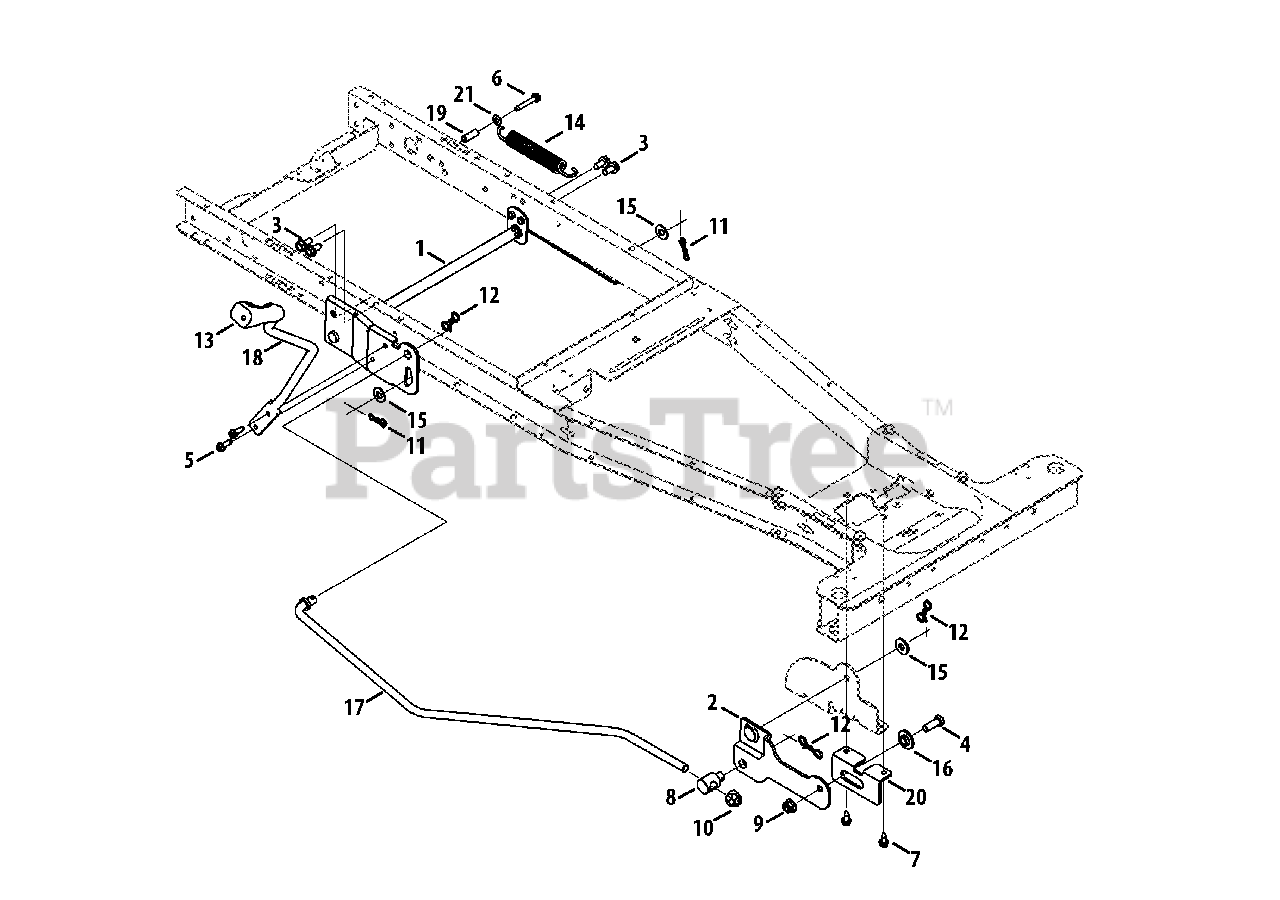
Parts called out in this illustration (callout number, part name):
1	Lift Assembly Shaft
2	Front Hanger Bracket Assembly
3	Tap Screw, 5/16-18, .750
4	Hex Head Screw, 3/8-16, 1.00
5	Tap Screw, 1/4-20, 0.750
6	Screw, 1/4-20, 1.50
7	Tap Screw, 1/4-20 X .625
8	Ferrule, .50 X .50
9	Flange Lock Nut, 3/8-16
10	Flex Lock Nut, 1/2-13
11	Bow-Tie Cotter Pin, 72
12	Bow-Tie Cotter Pin, 91
13	Grip Handle, 1/2
14	Extension Spring, .85 OD X 5.915 LG
15	Flat Washer, .406 X .875 X .059
16	Shoulder Spacer, .625 ID X .169
17	Lift Link Rod
18	Deck Lift Rod
19	Spacer, .260 x .375 x 1.030 LG
20	Front Deck Mounting Bracket
21	Flat Washer, .250 x .630 x .052
